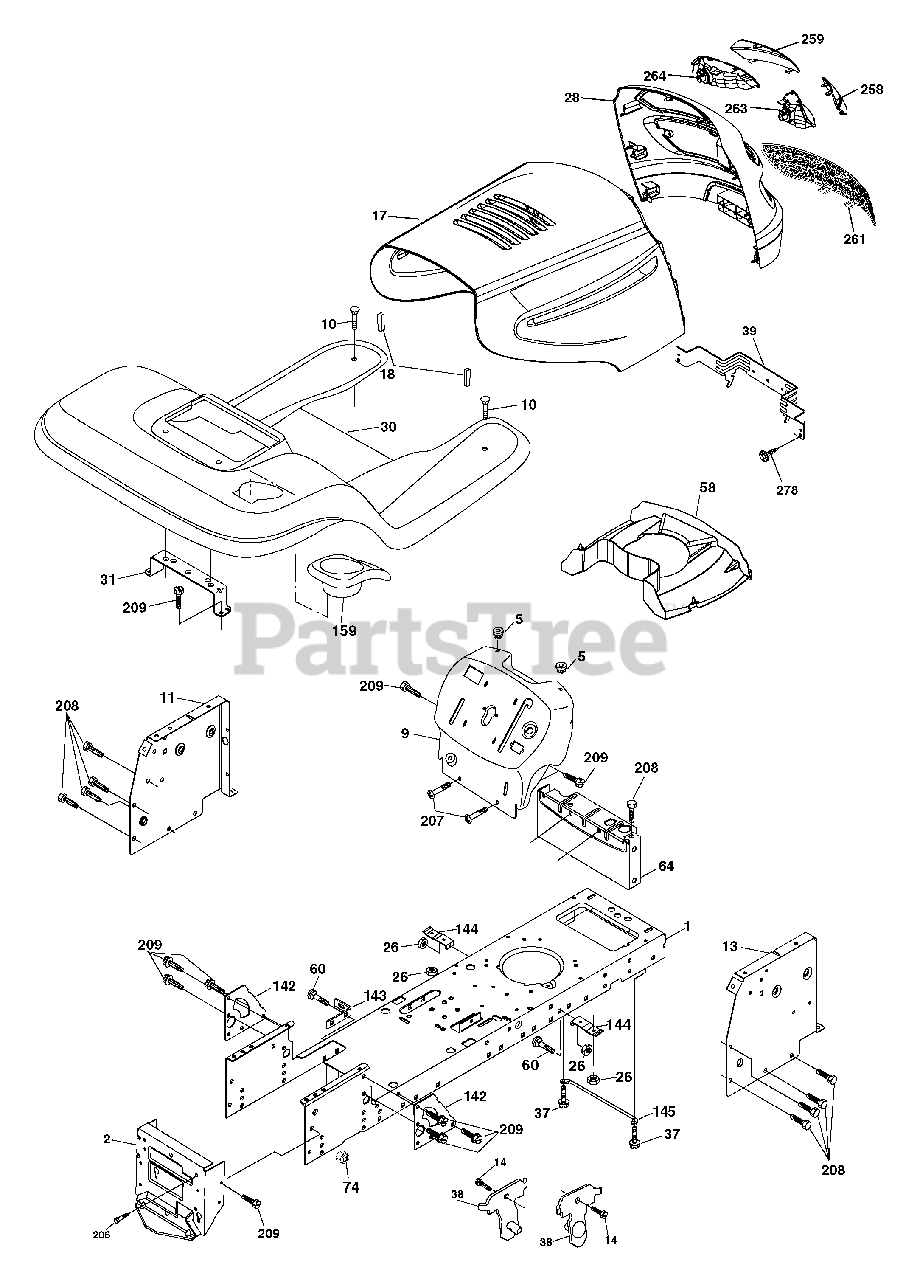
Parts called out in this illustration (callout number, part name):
1	Chassis
2	Drawbar
5	Bumper Hood/Dash
9	Dash P/L
10	Bolt Carriage 3/8-16 x 1
11	Panel Dash Lh
14	Screw Thdrol 3/8-16 x 1/2
17	Hood
18	Bumper Hood
26	Nut Lock Hex W/Ins 3/8-16 unc
28	Grille/Lens Asm
31	Bracket Fender
37	Screw Thdrol 6/16-18 x 1/2 TYT
38	Bracket Asm Pivot Mower Rear
39	Bracket Pivot
58	Duct Air
60	Bolt RDHD SHT SQNK 3/8-16 x 3/4
64	Dash Lower STLT
74	Nut, Crownlock 3/8-16
142	Plate Reinforcement STLT
143	Bracket, Swaybar
144	Bracket, Footrest
145	Rod Pivot Chassis/Hood
159	Cupholder
206	Bolt Shoulder 5/16-18
207	Screw Thdrol 5/16-18 x 1/2
208	Screw Thdrol 3/8-16 x 1/2
209	Screw Hexwsh Thdr 3/8-16 x 3/4
258	Lens Grille Pro RH
259	Lens Grille Pro LH
263	Bezel Grille RH
264	Bezel Grille LH
278	Screw 10 x 3/4 Single Lead Hex
